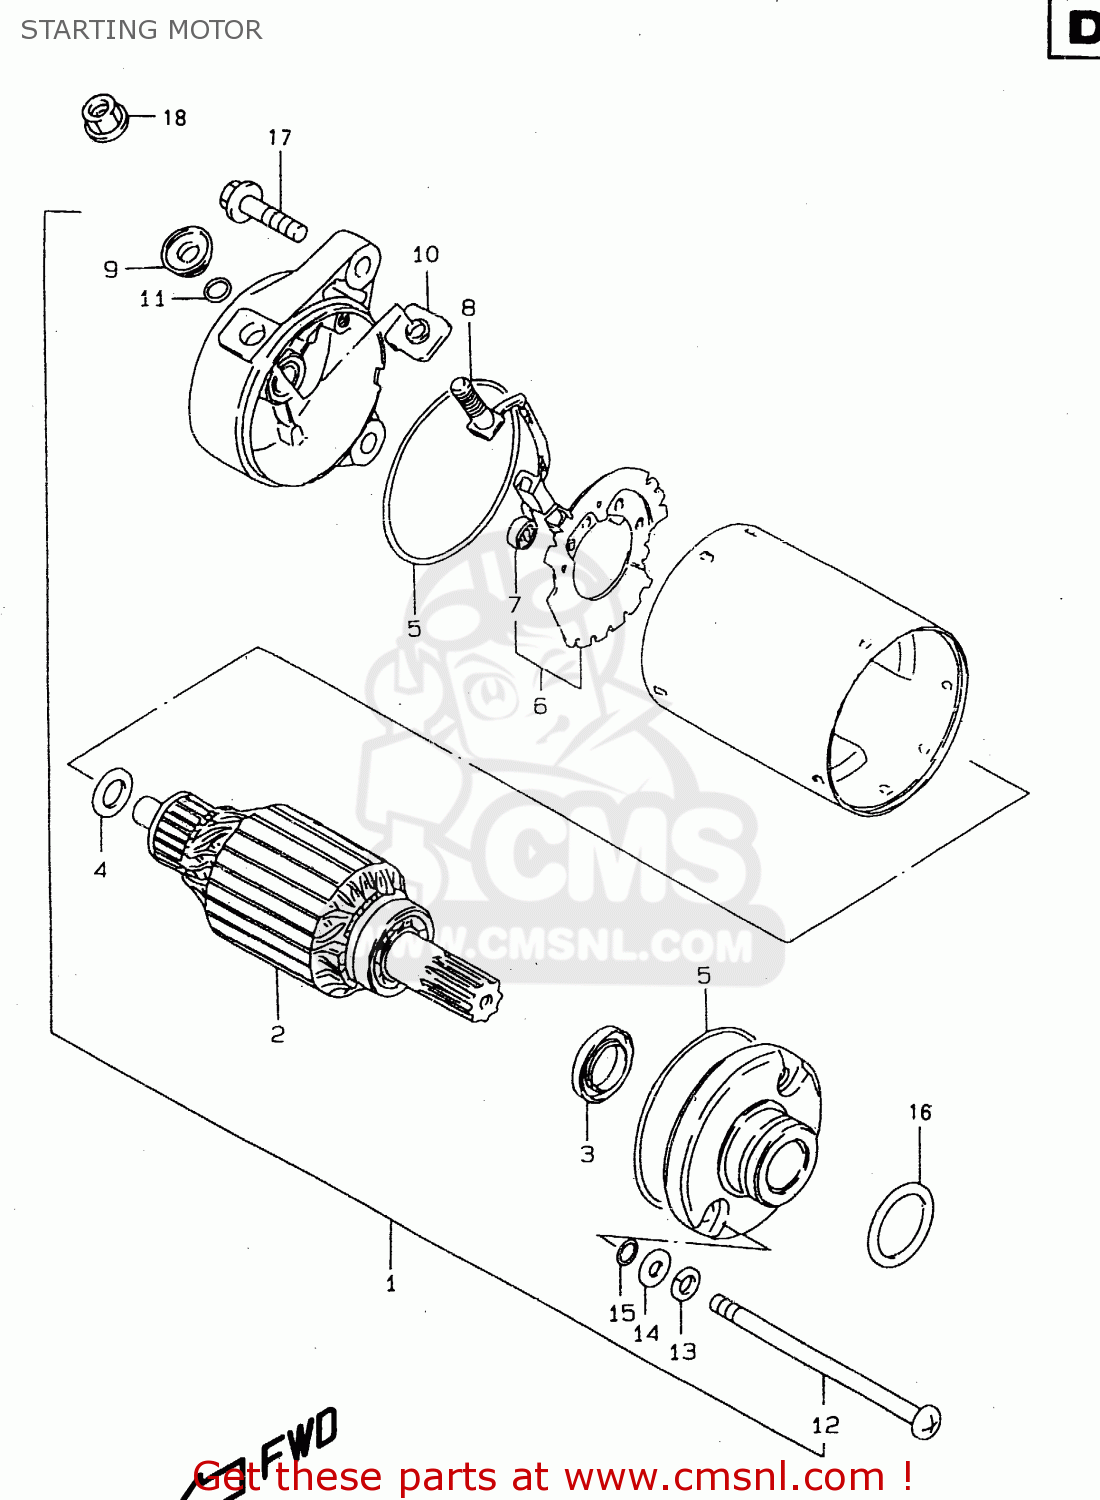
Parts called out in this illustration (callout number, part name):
1	MOTOR ASSY,STARTING
2	ARMATURE
3	SEAL,OIL
4	SHIM SET,STARTING MOTOR
5	O RING
6	HOLDER,BRUSH
7	SPRING
8	BRUSH SUB ASSY,STARTING MOTOR
9	BUSHING
10	BUSH,B
11	O RING
12	BOLT
13	WASHER,LOCK
14	WASHER
15	O RING
16	O RING(D:3,ID:24.5)
17	BOLT
18	NUT
